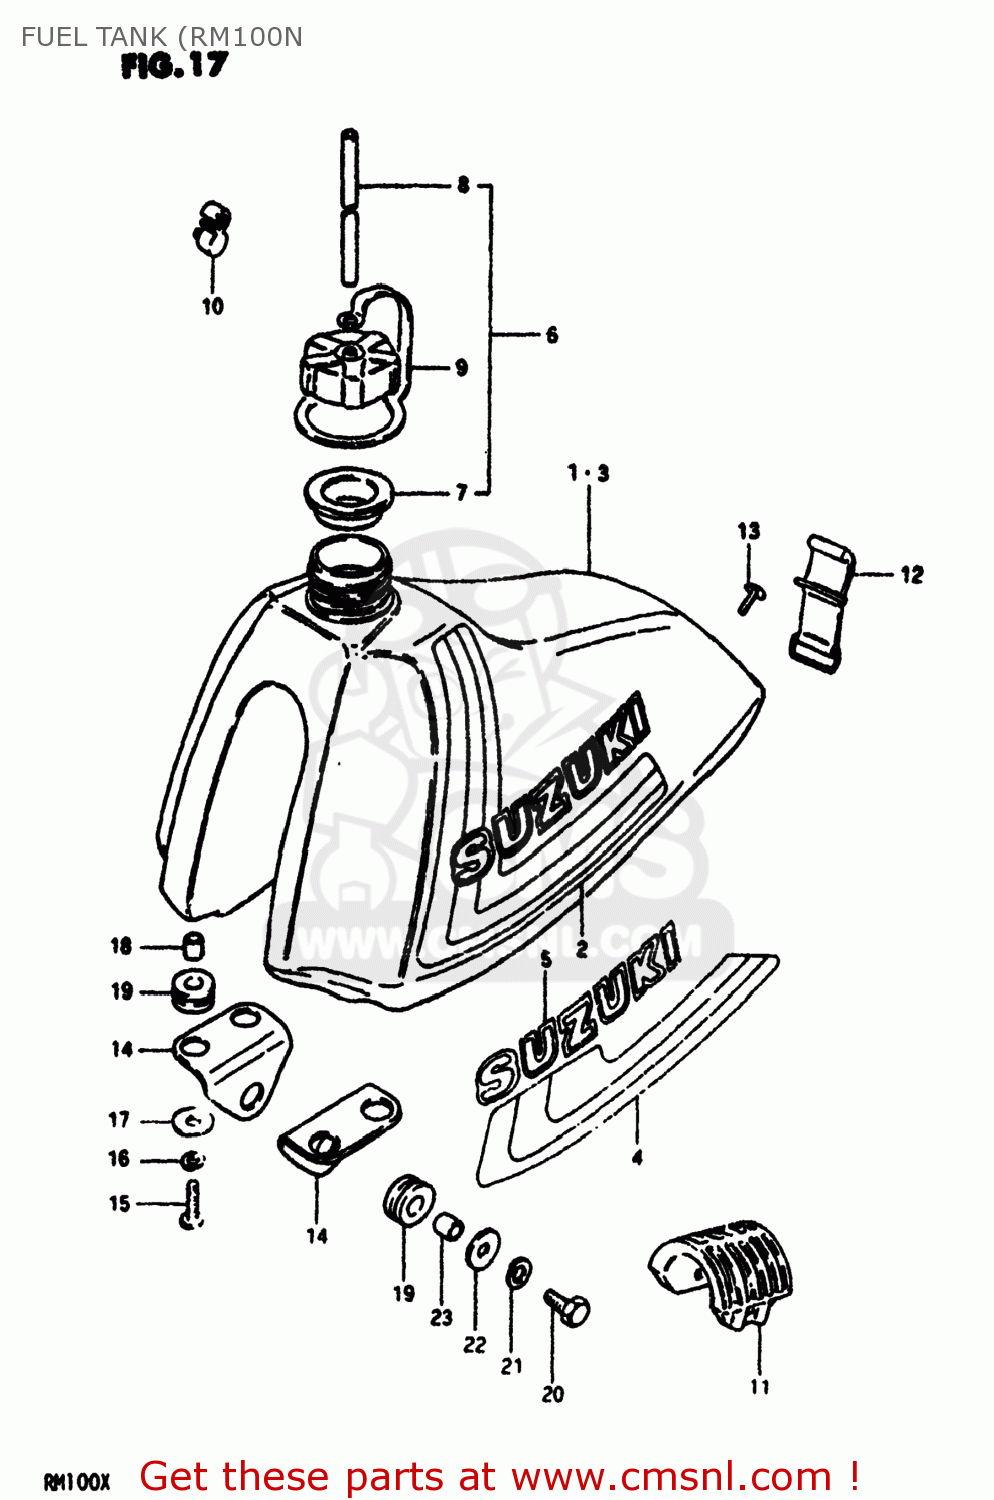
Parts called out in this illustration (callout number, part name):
1	TANK ASSEMBLY,FUEL
2	TAPE SET
3	TANK ASSEMBLY,FUEL
4	TAPE SET,FUEL TANK
5	EMBLEM
6	CAP SET,FUEL TANK
7	GASKET,FUEL TANK CAP (NAS)
8	HOSE
9	BAND,FUEL TANK CAP
10	CLAMP,FUEL TANK BREATHER HOSE
11	CUSHION,FUEL TANK
12	BAND
13	SCREW(6X18)
14	BRACKET,FUEL TANK
15	SCREW
16	LOCK WASHER
17	WASHER (6.5X24X1.6)
18	SPACER(6.8X12X11)
19	CUSHION
20	HEXAGON BOLT
21	LOCK WASHER
22	WASHER (8.2X24X1.6)
23	SPACER (8.8X12X11)
